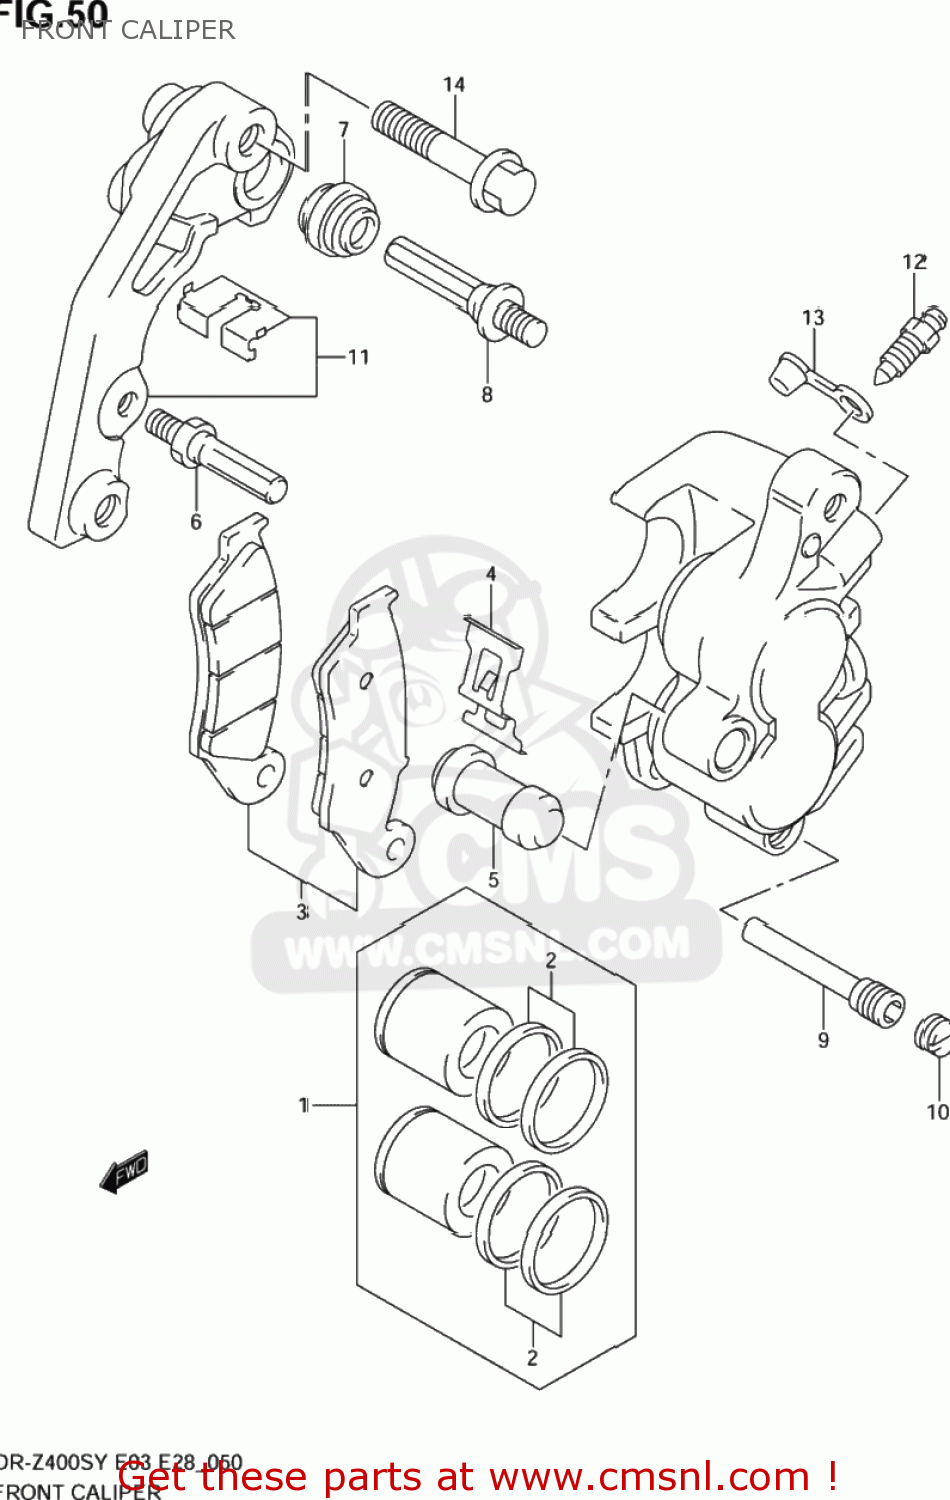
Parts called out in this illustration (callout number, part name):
1	PISTON SET
2	SEAL SET,PISTON
3	PAD SET (NAS)
4	SPRING,PAD
5	BOOT
6	BOLT
7	BOOT
8	PIN
9	PIN,HANGER
10	PLUG,PIN
11	BRACKET
12	BLEEDER
13	CAP,BLEEDER
14	BOLT(8X40)
